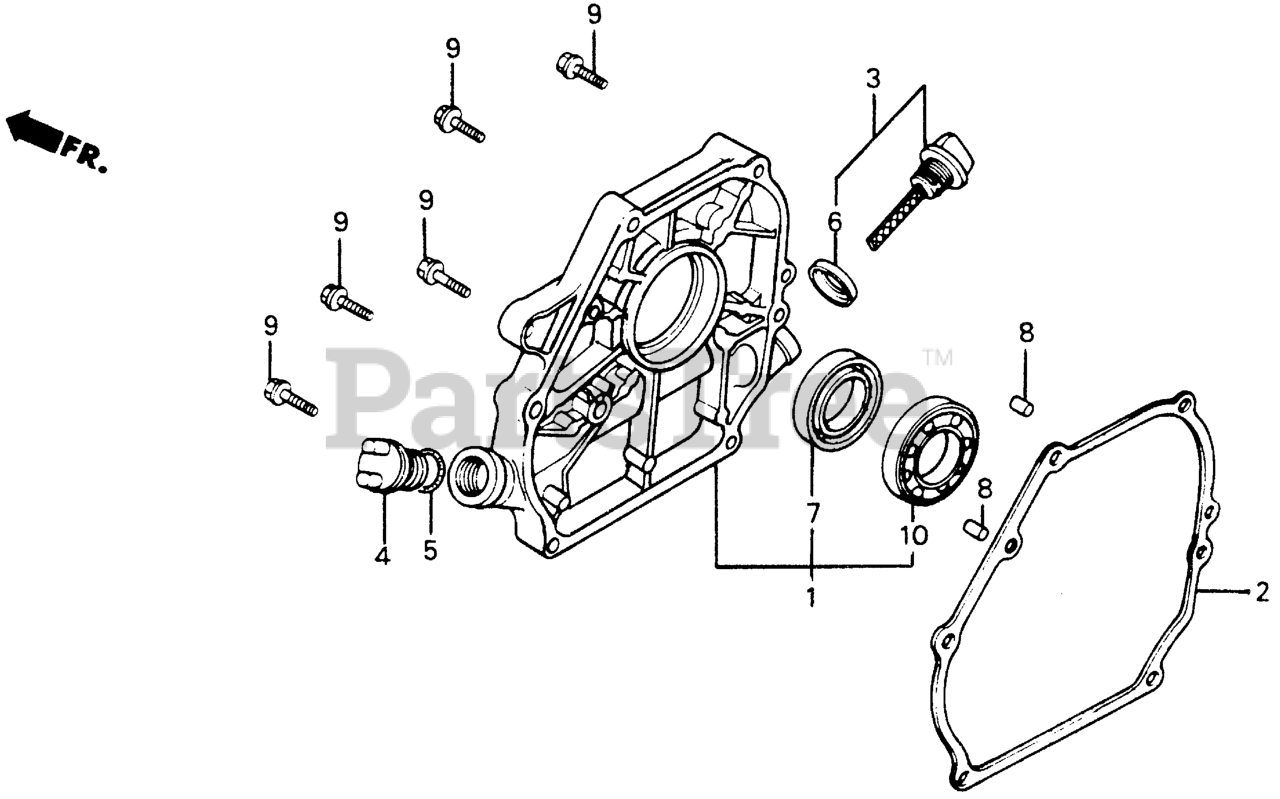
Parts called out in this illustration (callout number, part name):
1	COVER ASSY., CRANKCASE
2	GASKET, CASE COVER (NON-ASBESTOS)
3	CAP ASSY., OIL FILLER
4	CAP, OIL HOLE
5	GASKET, OIL FILLER CAP Use from Engine SN 1391010.
6	GASKET, OIL FILLER CAP
7	OIL SEAL (25X41X6)
8	PIN A, DOWEL (8X14)
9	BOLT, FLANGE (8X32)
10	BEARING, RADIAL BALL (6205)
